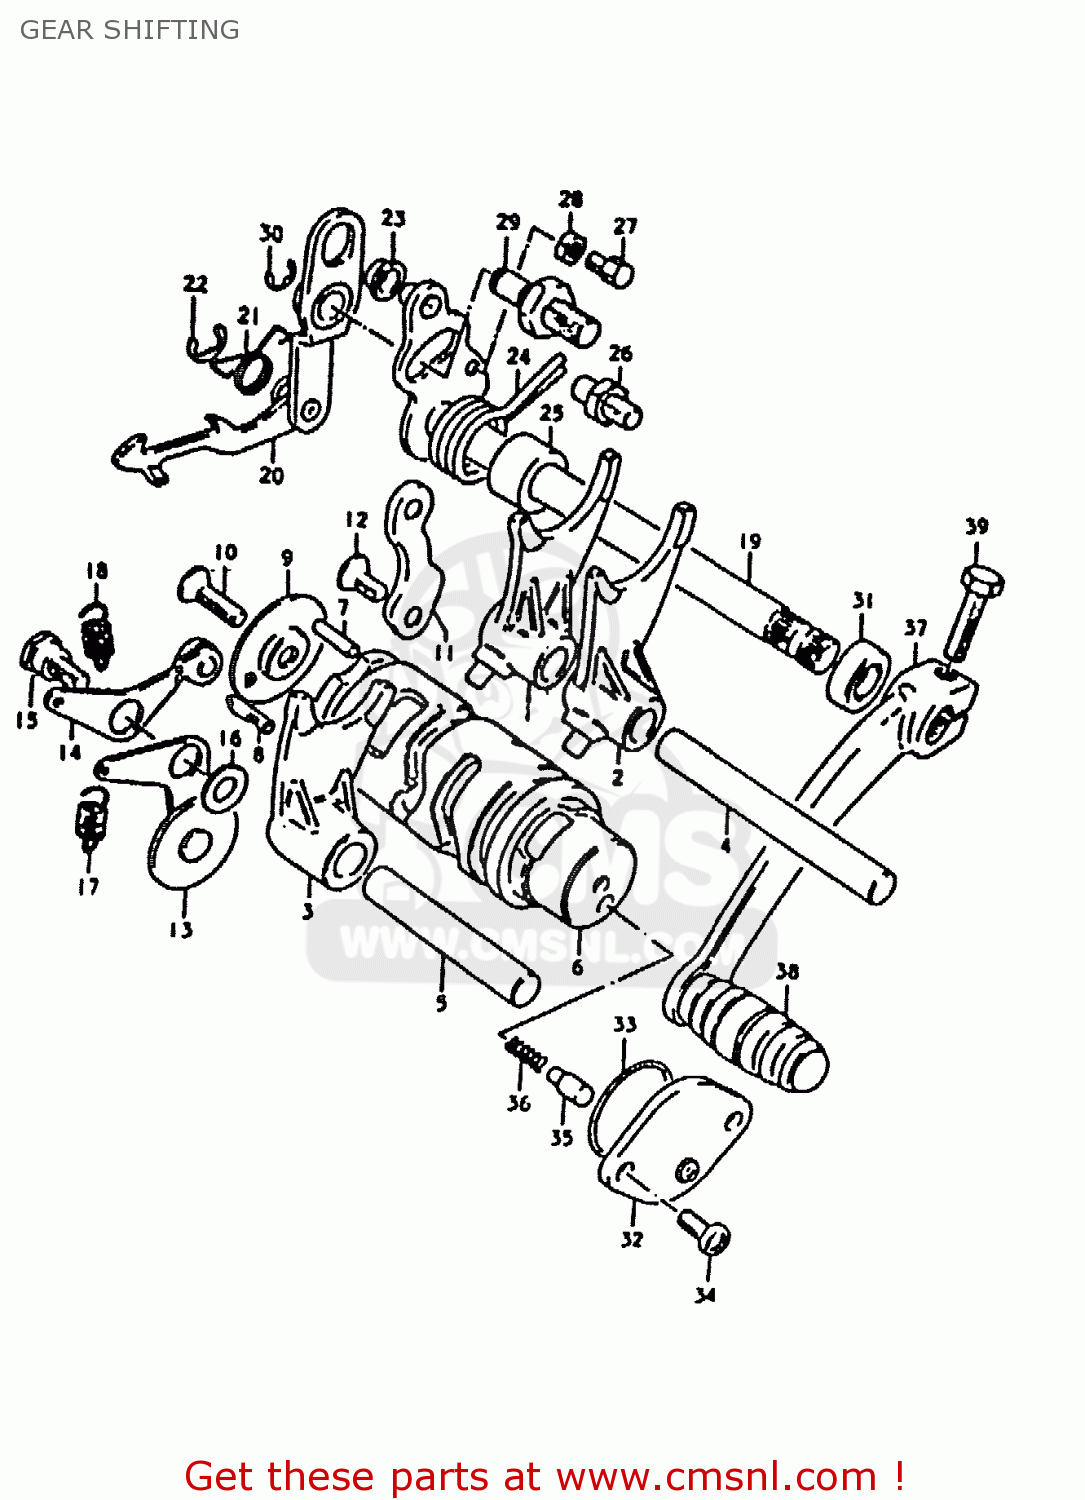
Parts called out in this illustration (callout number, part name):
1	FORK,GEAR SHIFT NO.1
2	FORK,GEAR SHIFT NO.2
3	FORK,GEAR SHIFT NO.2
4	SHAFT,GEAR SHIFT FORK
5	SHAFT,GEAR SHIFT FORK
6	CAM,GEAR SHIFT
7	PIN(4X15.8)
8	PIN
9	RETAINER,GEAR SHIFT CAM DR PIN
10	SCREW
11	GUIDE,GEAR SHIFT CAM
12	SCREW
13	STOPPER,GEAR SHIFT CAM
14	STOPPER,GEAR SHIFT CAM NEUTRAL
15	BOLT(6X18.3)
16	WASHER
17	SPRING
18	SPRING
19	SHAFT,GEAR SHIFT
20	PAWL,GEAR SHIFTING
21	SPRING
22	E RING
23	SPACER(7X10X5)
24	SPRING
25	SPACER(12X20X15.3)
26	STOPPER,GEAR SHIFT CAM
27	BOLT,GEAR SHAFT RETURN SPR SET
28	NUT 6MM
29	STOPPER,GEAR SHIFT CAM
30	E RING 6MM
31	OIL SEAL
32	BODY,GEAR SHIFT SWITCH
33	O-RING (D:2.4 ID:26.2)
34	SCREW
35	PIN(5X15.5)
36	SPRING
37	LEVER ASSEMBLY,GEAR SHIFTING
38	RUBBER,GEAR SHIFT PEDAL
39	BOLT
